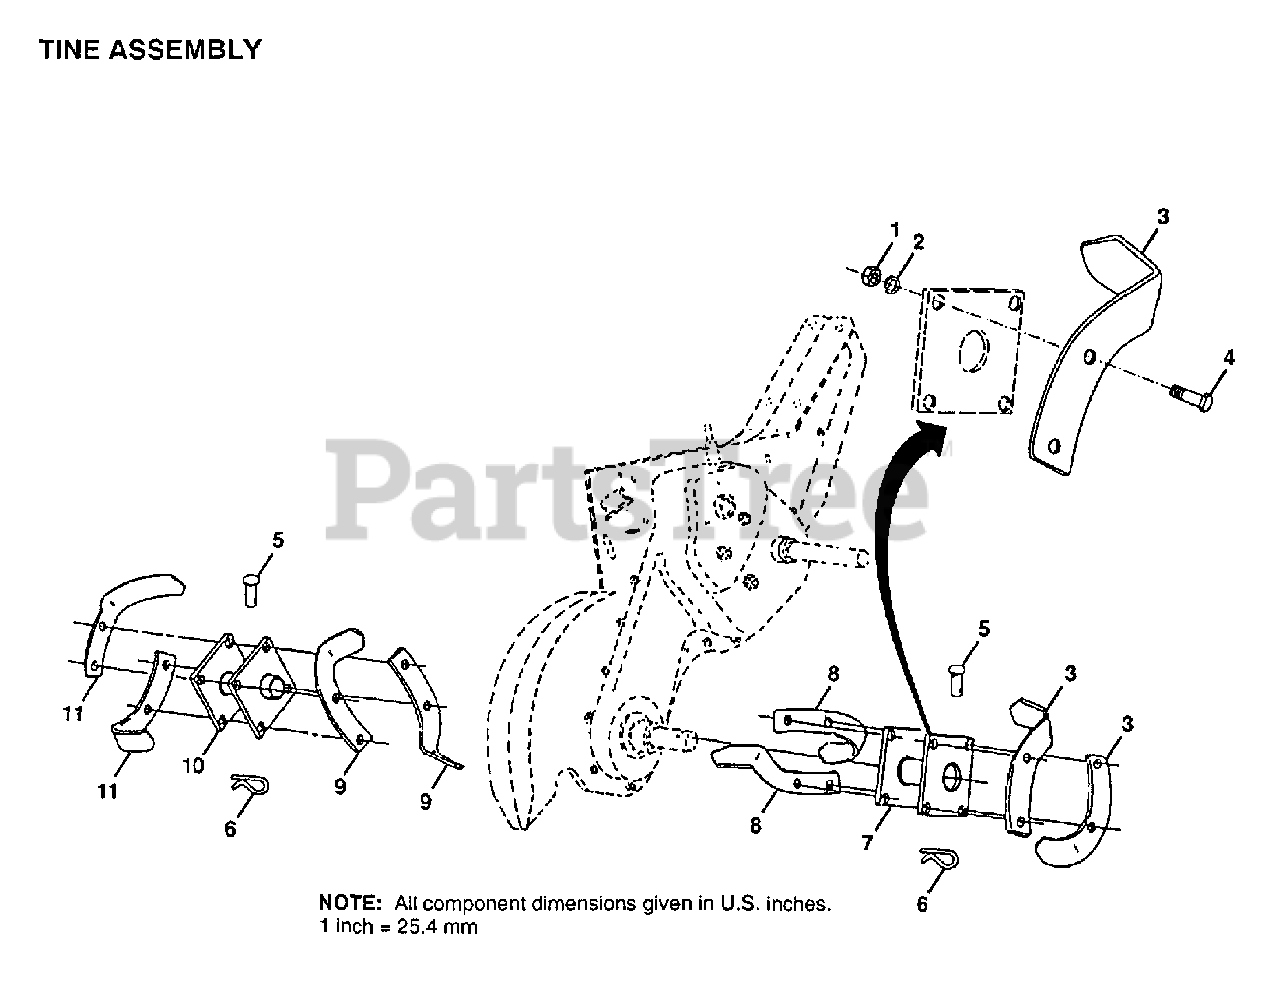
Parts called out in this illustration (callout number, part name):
2	LOCKWASHER
4	BOLT
5	PIN.CLEVIS.SHEAR
6	RETAINER.SPRING
7	ASM HUB&PLATE RH
8	"TINE.RH.12"""
9	"TINE.LH.12"""
10	ASM HUB&PLATE LH
